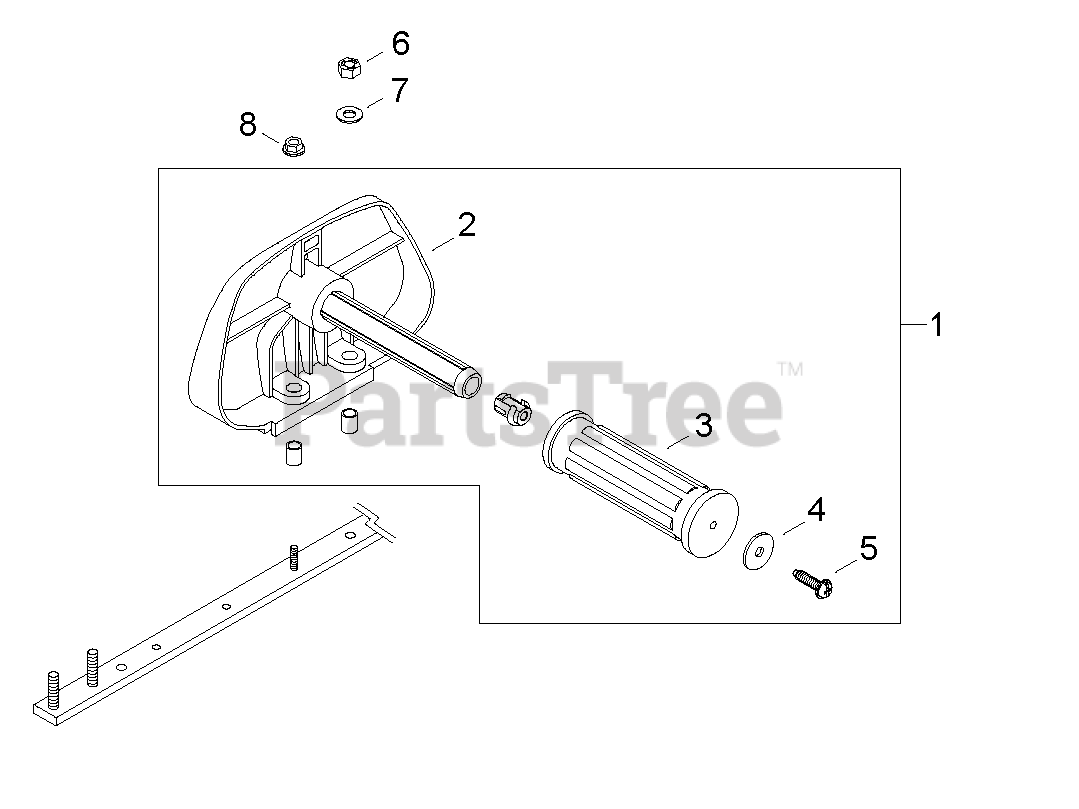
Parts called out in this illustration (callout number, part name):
1	HANDLE ASSY - FRONT
2	HANDLE - FRONT
4	WASHER - 5
5	SCREW - 5X20
6	NUT - 6
7	WASHER - 6
8	NUT - 5 -- FLANGE
